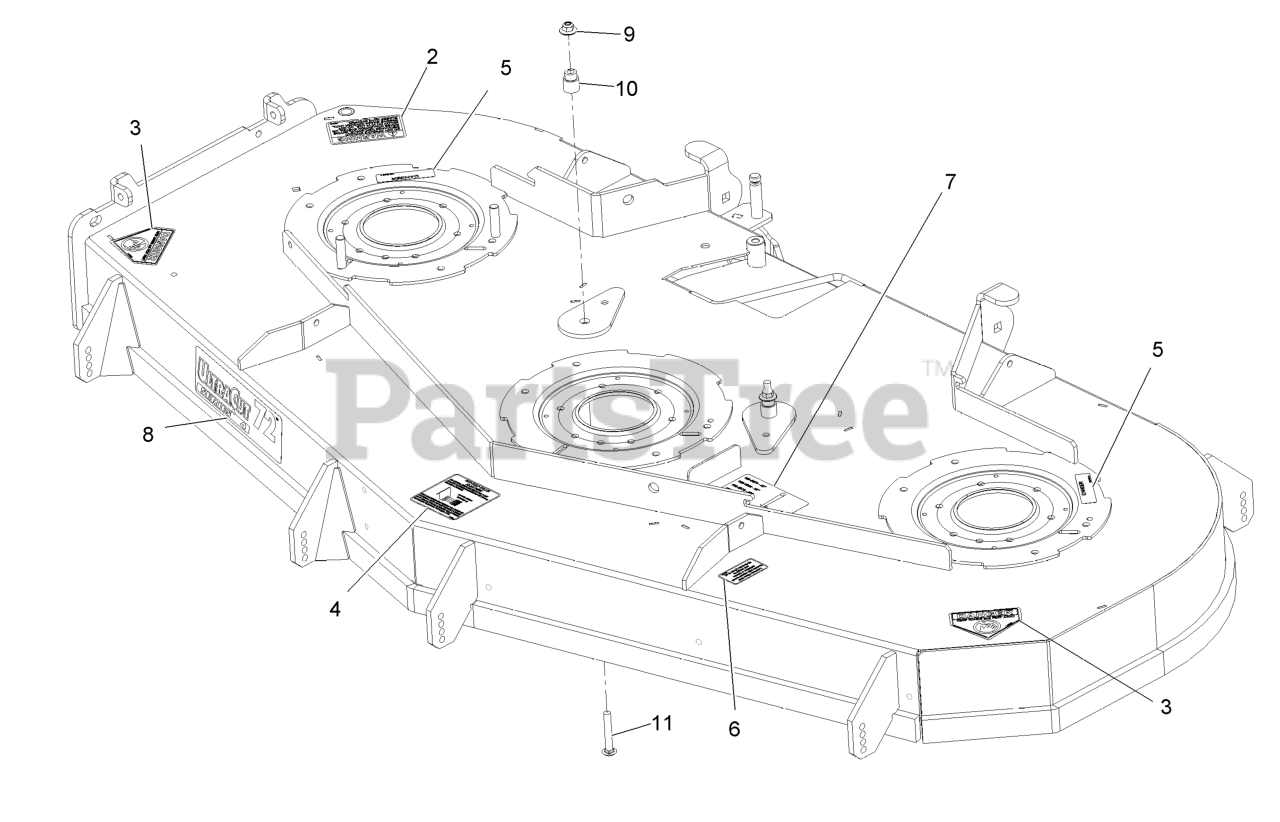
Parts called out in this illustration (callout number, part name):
2	DECAL-WARNING, DISCHARGE
3	DECAL-DANGER
4	DECAL,ANTISCALP
5	DECAL-COVER, MISSING
6	DECAL,BOLT TORQUE
7	DECAL,BELT ROUTING
8	DECAL,ULTRACUT 72 SERIES
9	Nut-Nyloc 3/8-16 Flg
10	BUSHING-IDLER
11	SCREW-CARR
